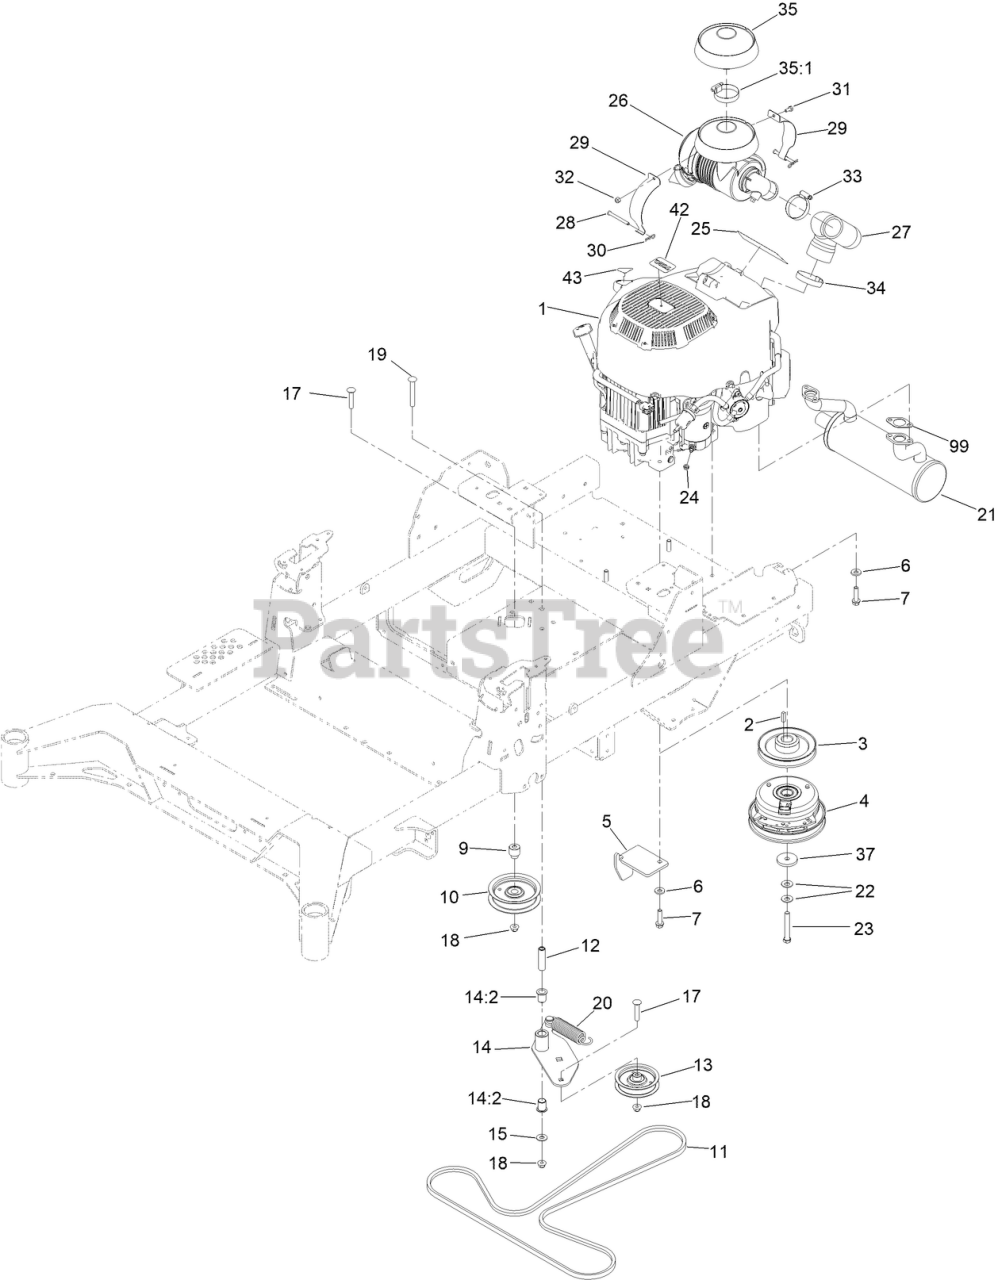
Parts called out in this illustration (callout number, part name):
1	ENGINE-2P77F-HD
3	SHEAVE-ENGINE
4	CLUTCH 6.75, 105 FTLB, 1.00 DD
5	ANCHOR-CLUTCH
6	WASHER-BELLEVILLE
7	SCREW-HWH
9	BUSHING-IDLER
10	PULLEY-IDLER, FLAT
11	BELT-V
12	BUSHING, IDLER PIVOT
13	PULLEY-IDLER, FLAT
14	IDLER ARM ASM
14:2	BUSHING-FLANGE
15	WASHER-FLAT
17	BOLT-CARRIAGE
18	NUT-HF, NI
19	SCREW-CARR
20	SPRING-EXTENSION
21	MUFFLER
22	WASHER-SPRING
23	SCREW-HH W/LOCTITE
24	NUT-HF
26	AIR CLEANER ASM
27	HOSE-INTAKE
28	PIN-CLEVIS
29	STRAP-CANISTER, AIR
30	PIN-COTTER
31	SCREW-HH
32	NUT-HEX
33	CLAMP-HOSE
34	CLAMP-HOSE
35	RAIN CAP KIT
35:1	CLAMP-HOSE
37	WASHER-CLUTCH
43	DECAL-DRAIN, OIL
99	GASKET-EXHAUST
